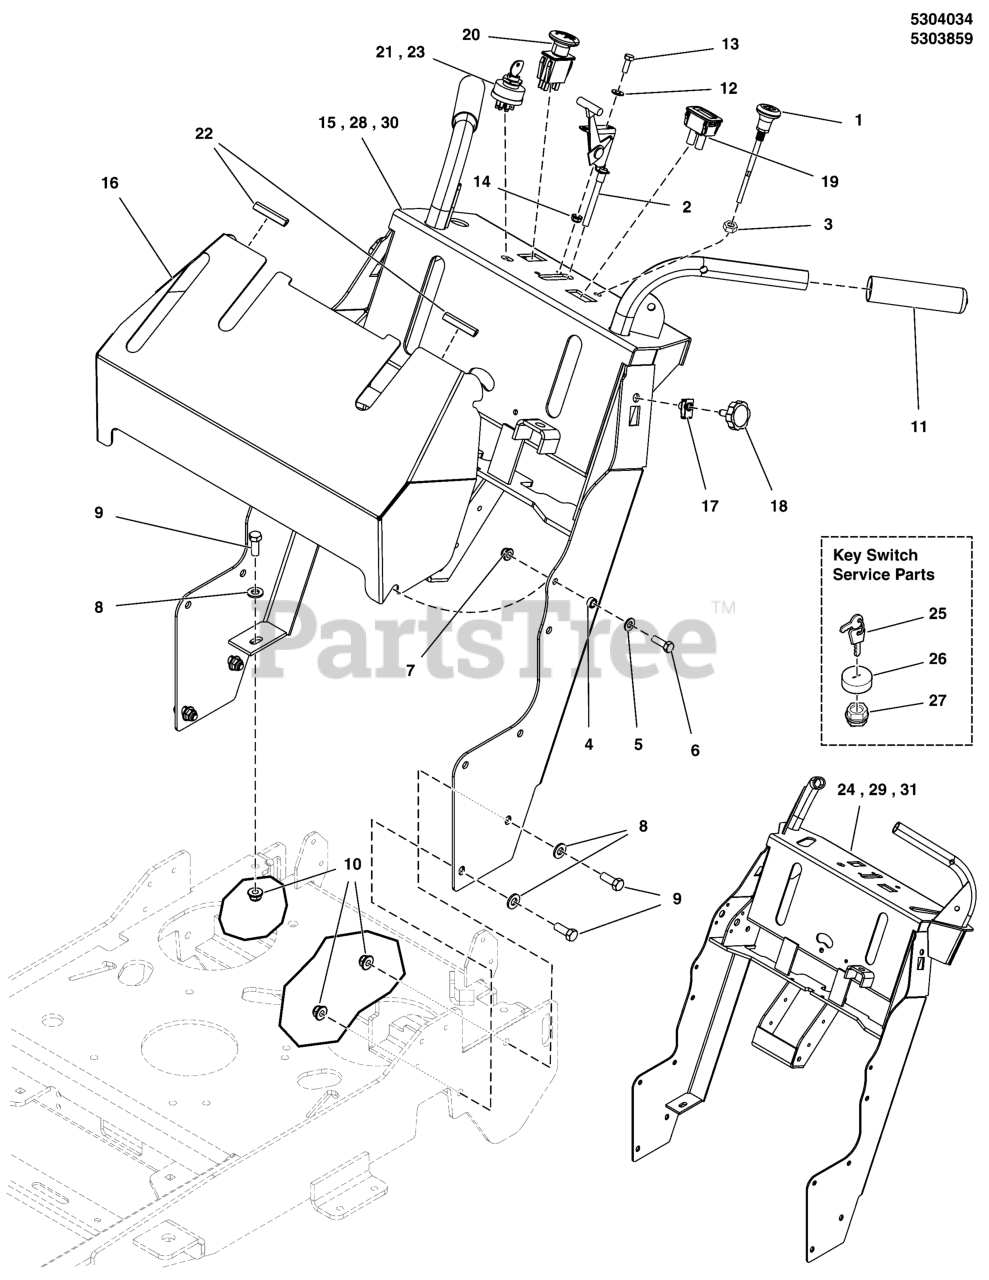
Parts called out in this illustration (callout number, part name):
1	CABLE, CHOKE CONTROL, 51"
2	CABLE, THROTTLE, 48" DETENTED
2	CABLE THROTTLE, 48"
3	NUT, HEX 3/8-24
4	SPACER, .33 X .50 X .25, PM, CZ
5	WASHER, 5/16" SAE
6	BOLT, 5/16-18 X 1 GD5 CZ
7	NUT, 5/16-18 HEX NYLOCK FLANGE
8	WASHER, 3/8 GD.9 FLAT
9	BOLT, 3/8-16 X 1" GD5 CZ
10	NUT, 3/8-16 HEX NYLOCK FLANGE
11	GRIM, FOAM, .940" ID X 4.62" X .187", BLK
12	WASHER, 1/4 SAE
13	BOLT, 1/4-20 X 3/4 GD5 CZ
14	NUT, 1/4-20 HEX NYLOCK FLANGE
15	** WELD, HANDLE BARS, FW25 - RED
16	ASSM, HB GUARD W/DECALS, SW25 - DOM
17	BODY CLIP, 5/16-18-7GA MATERIAL
18	KNOB, 5/16-18 X 1.00, ROSETTE, BLK
19	* HOUR METER, ASSEMBLE
20	PTO SWITCH, MOMENTARY, SMALL KNOB
21	SWITCH, IGNITION, 2 POST
22	BLACK BODY MOLDING, 3" LONG
23	SWITCH, IGNITION, 6 POST
24	** WELD, HANDLE BARS, FW25 CC - RED
25	KEY, IGNITION MOLDED SET
26	COVER, PLASTIC, SNAP ON
27	PLASTIC NUT
28	** WELD, HANDLE BARS, FW25 - RED
29	** WELD, HANDLE BARS, FW25 CC - RED
30	** WELD, HANDLE BARS, W25 - STND - RED
31	** WELD, HANDLE BARS, W25 - CC - RED
